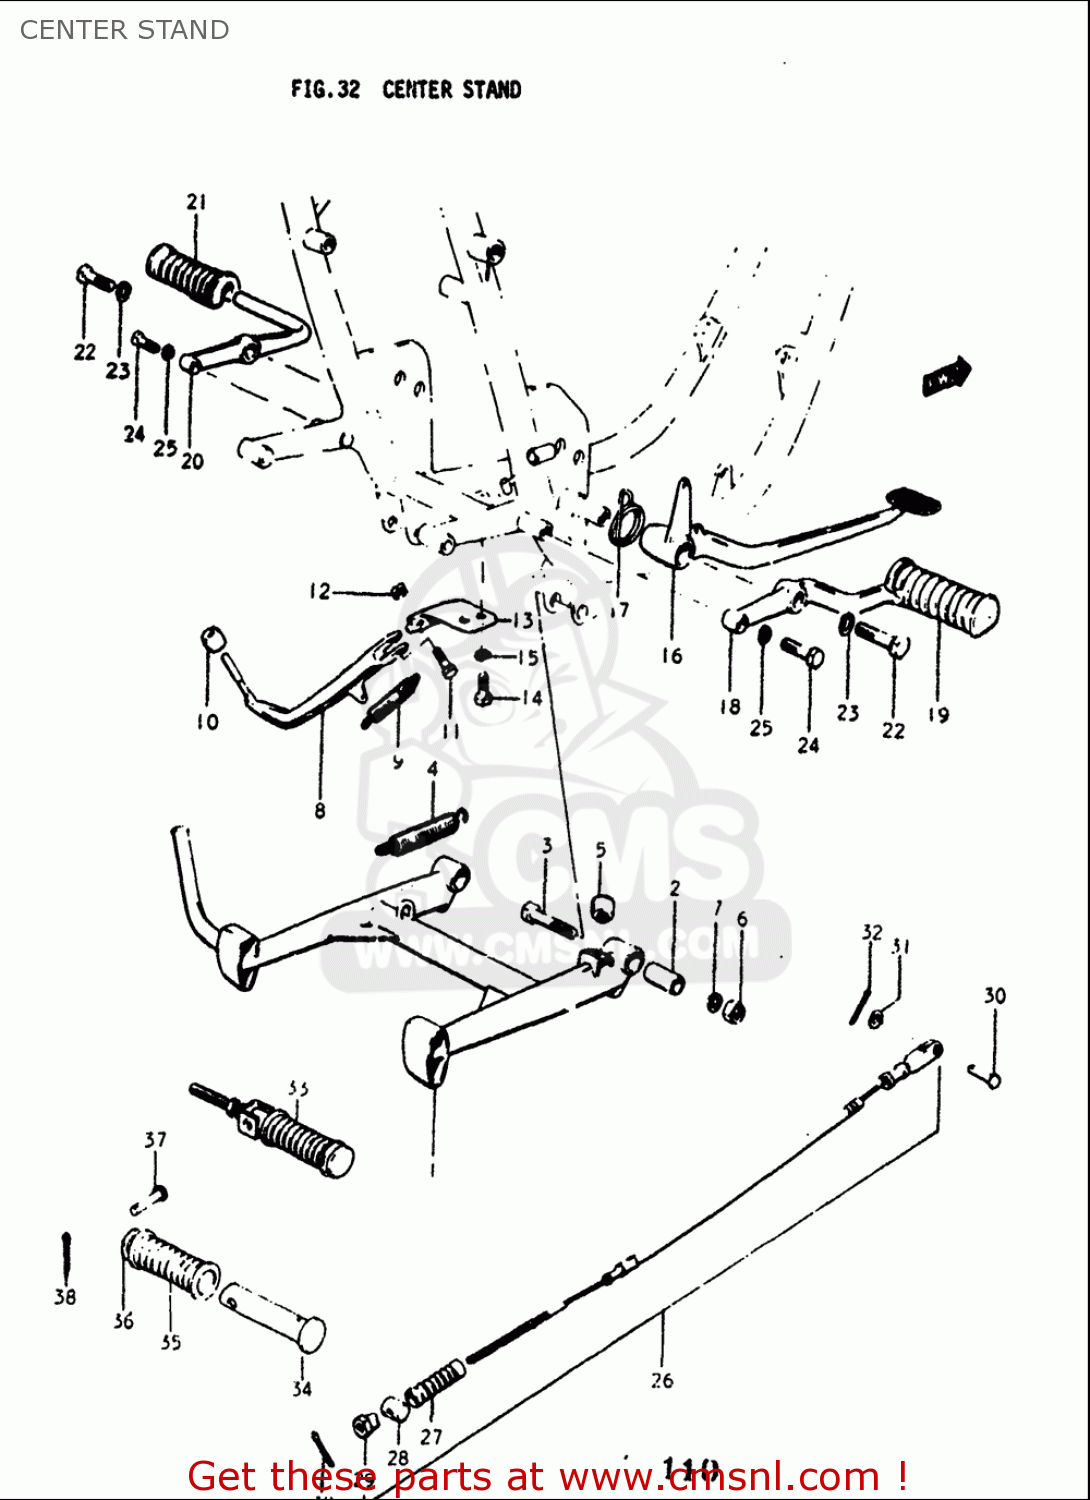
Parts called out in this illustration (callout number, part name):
2	SPACER(10.5X16X30)
3	BOLT(10X48)
4	SPRING
5	CUSHION
6	NUT
7	WASHER,LOCK
8	STAND,PROP
9	SPRING
10	CUSHION
11	BOLT(10X27)
12	NUT
13	BRACKET,SIDE STAND
14	BOLT
15	WASHER,LOCK
17	SPRING
19	RUBBER,FR FOOTREST,R
21	RUBBER,FR FOOTREST
22	BOLT
23	WASHER,LOCK
24	BOLT
25	WASHER,LOCK
26	CABLE ASSY,RR BRAKE
27	SEAL,DUST
28	PIN(13X18)
29	NUT
30	PIN(L:17.5)
31	WASHER
32	PIN
33	FOOTREST ASSEMBLY,REAR
34	BAR,FOOTREST RUBBER
35	RUBBER,PILLION FOOTREST
36	WASHER(19.5X32X2)
37	PIN
38	PIN
